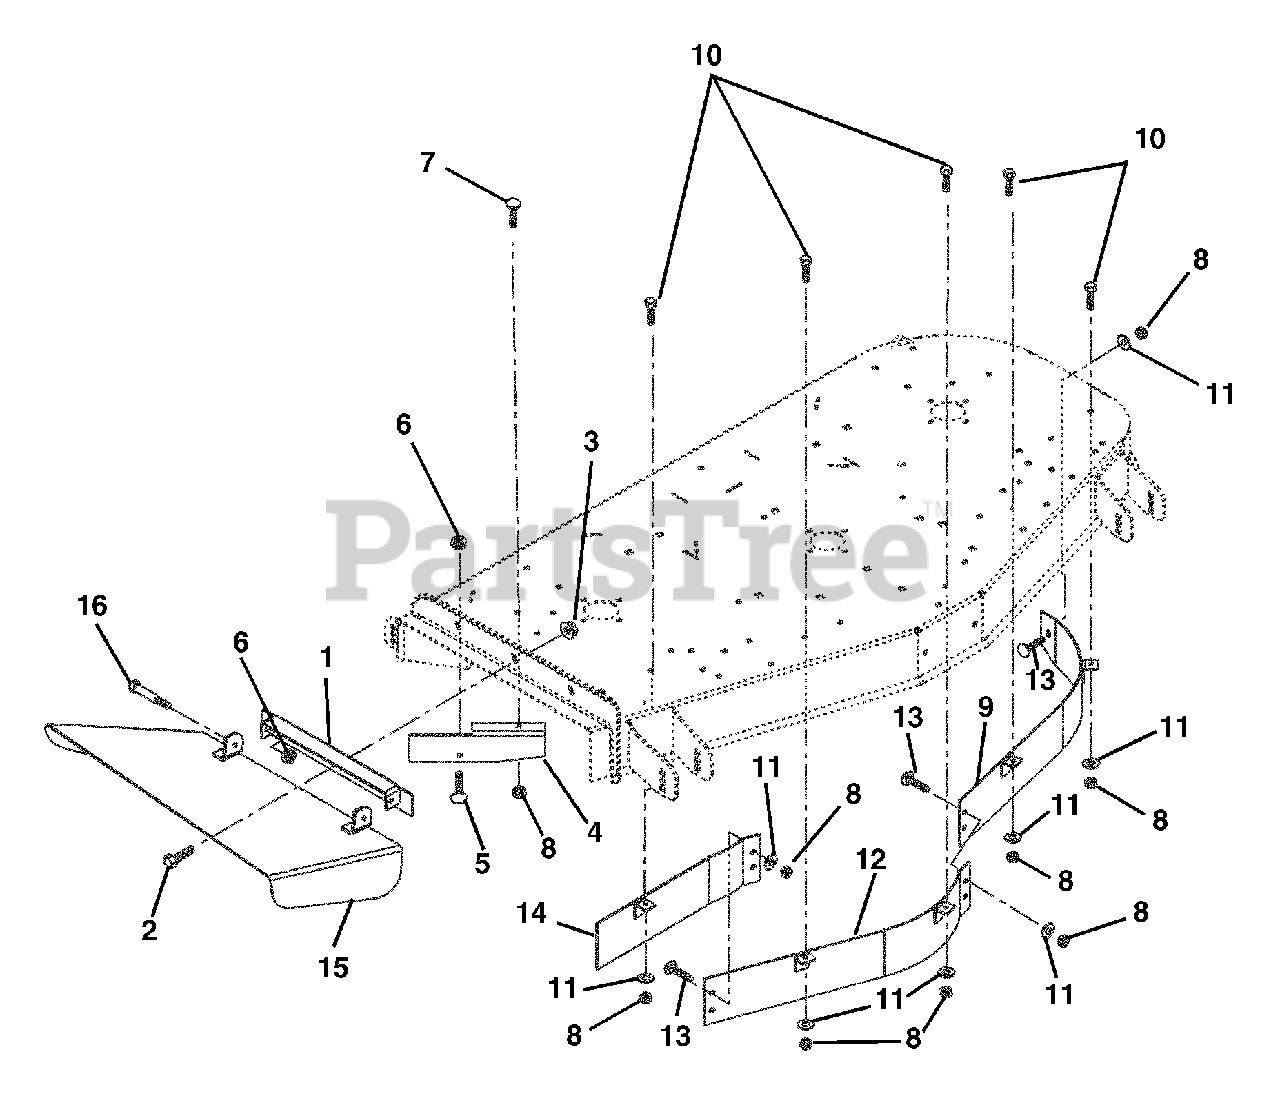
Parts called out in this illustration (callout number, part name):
1	Weldment, Discharge Chute Bracket
2	Bolt-Hex .38-16 x 1.00 Grade 5
3	Nut-Locking-Flange .38-16
4	Deflector, 72"
5	Bolt-Round Head Square Neck .38-16 x 1.00 Grade 2
6	Nut-Locking-Center .38-16
7	Bolt-Round Head Square Neck .31-18 x 1.00 Grade 5
8	Nut-Locking-Nylon .31-18
9	Weldment, 72" Left Hand Baffle
10	Bolt-Hex .31-18 x 1.00 Grade 5
11	Washer-Flat-Steel .312 x .734 x .065
12	Weldment, 72" Center Baffle
13	Bolt-Round Head Square Neck .31-18 x .75 Grade 2
14	Weldment, 72" Right Hand Baffle
15	Weldment, Discharge Chute 72"
16	Bolt-Shoulder .38-16 x .38
17	72" S.D. Mulch Kit
18	72" Discharge Cover Kit
